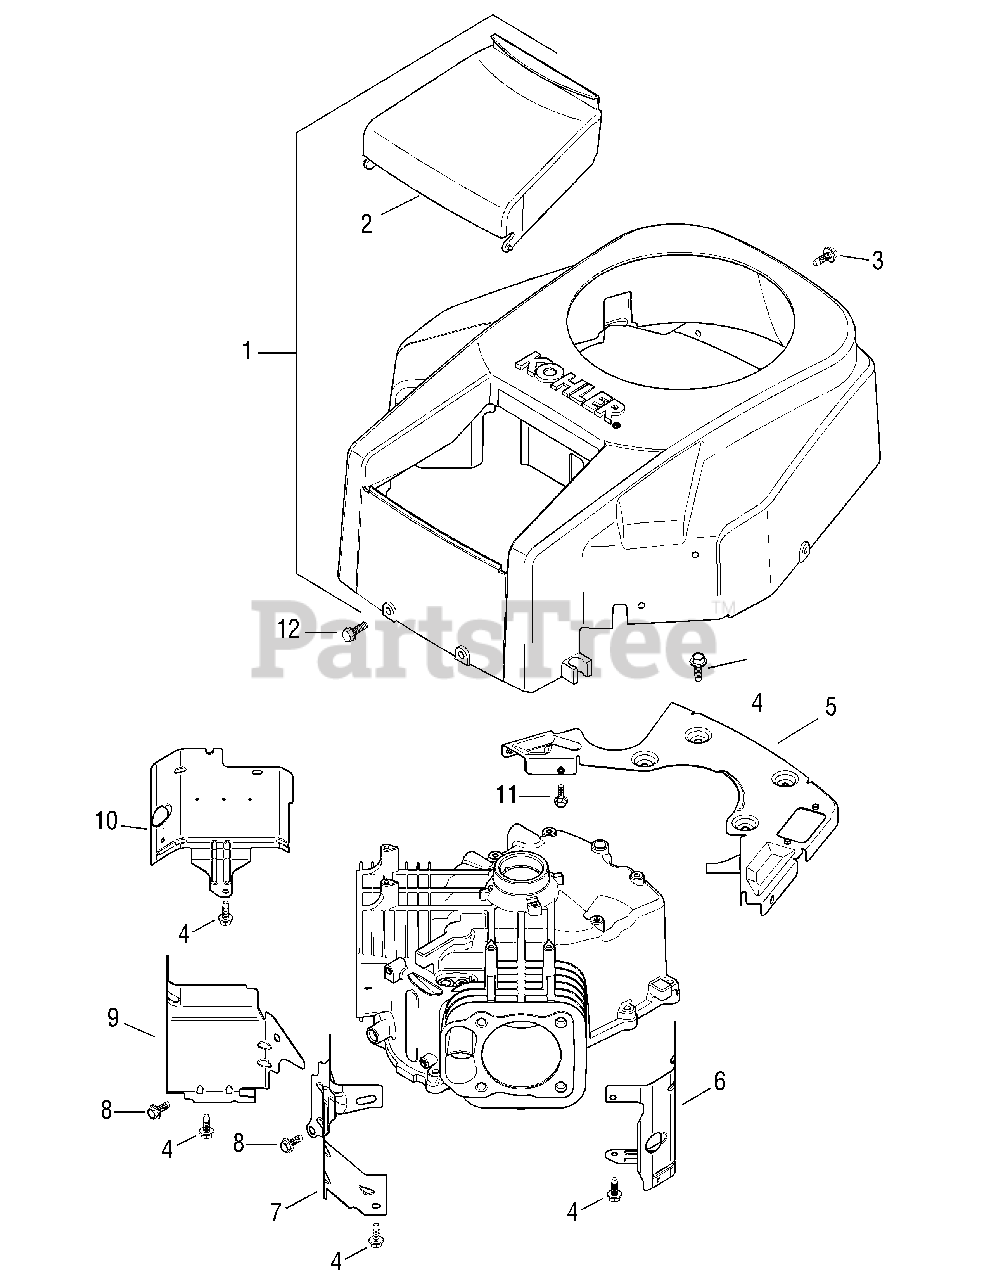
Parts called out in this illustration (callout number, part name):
1	Housing, blower
2	Cover, air cleaner
3	Screw, hex. flange M5x0.8x16
4	Screw, hex. flange M6x1.0x16
5	Plate, backing w/rectifier-regulator opening
6	Baffle, cylinder barrel - #2 side
7	Baffle, valley - #2 side
8	Screw, hex. flange M5x0.8x10
9	Baffle, valley - #1 side
10	Baffle, cylinder barrel-#1 side (SLT 1554)
10	Baffle, cylinder barrel-#1 side (SLT 1550)
11	Screw, hex. flange M5x0.8x20
12	Screw, hex. cap M6x1.7x18
